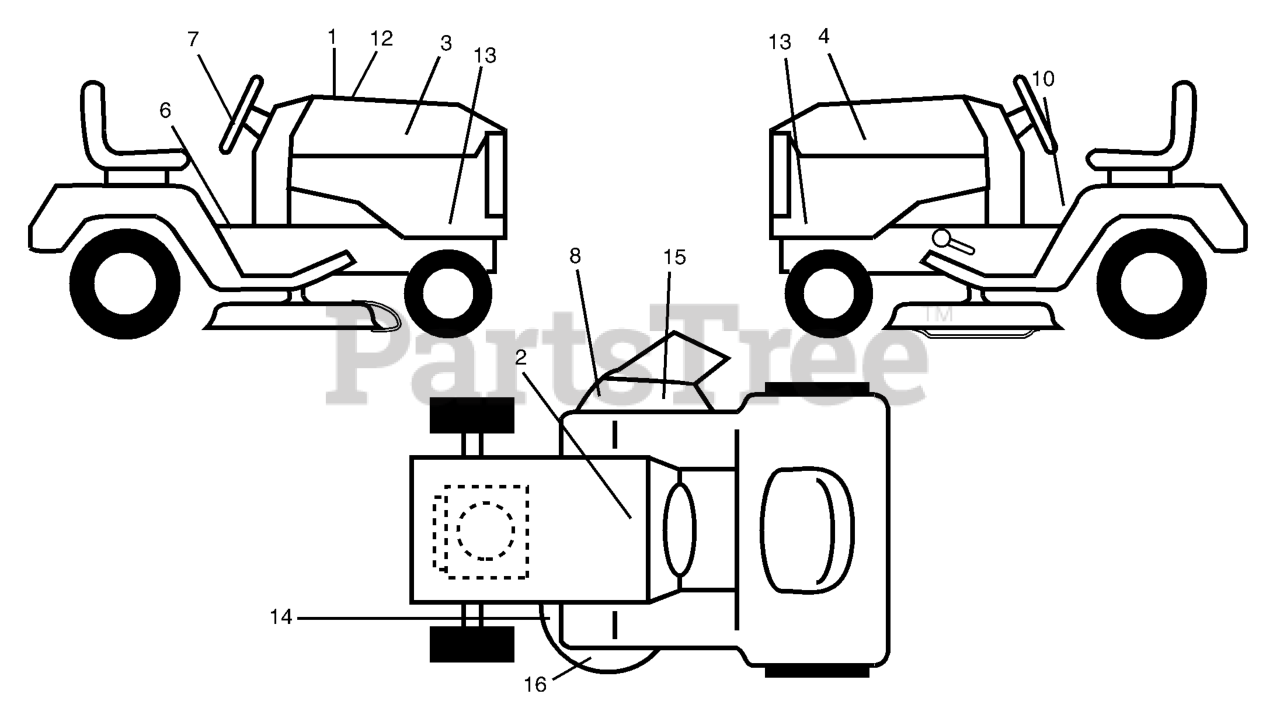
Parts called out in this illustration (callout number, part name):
1	DECAL HOOD CUST. RESP.
2	DECAL BTRY SYMBOLS
3	DECAL, HOOD RH
4	DECAL, HOOD LH
7	DECAL.STEERING.HUSQ.BLUE
8	DECAL.WARN.KEEP.HAND.AWAY
10	DECAL FENDER DANGER
12	DECAL, HOOD
14	DECAL V BELT SCHEMATIC
15	DECAL DECK "B" 42"
